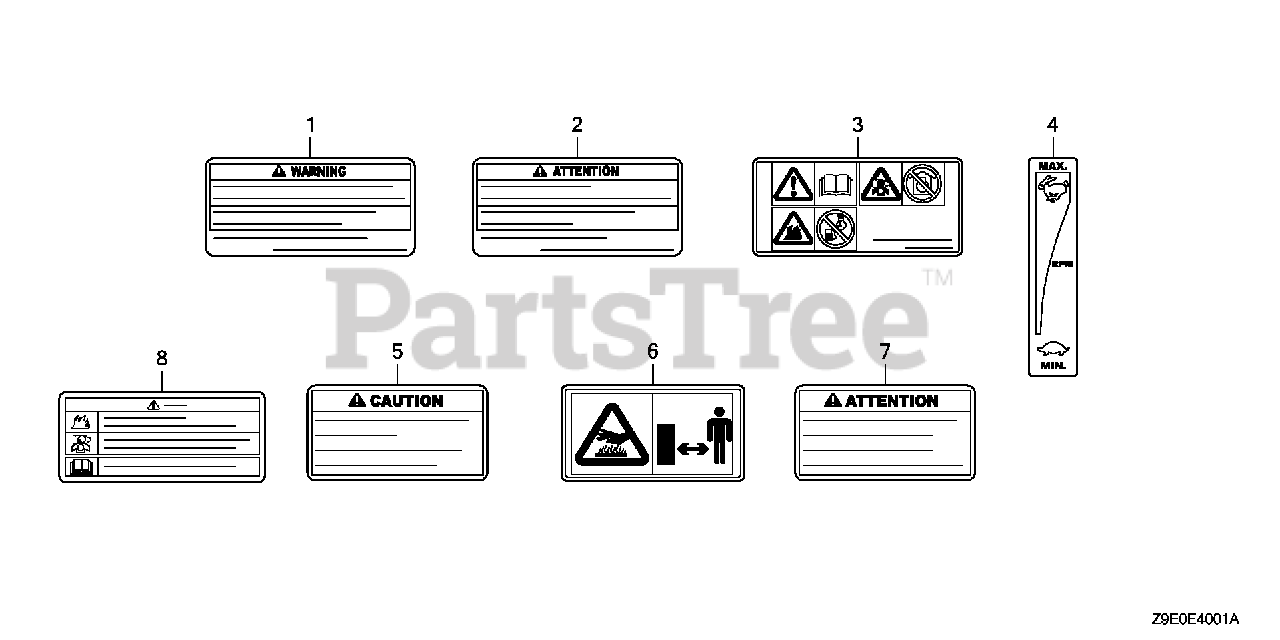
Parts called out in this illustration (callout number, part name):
2	MARK, OPERATOR CAUTION (FRENCH)(MADE IN JAPAN)
3	MARK, OPERATOR CAUTION (PICTOGRAPH)
5	MARK, EX. CAUTION (ENGLISH)
6	MARK, EX. CAUTION (PICTOGRAPH)
7	MARK, EX. CAUTION (FRENCH)
